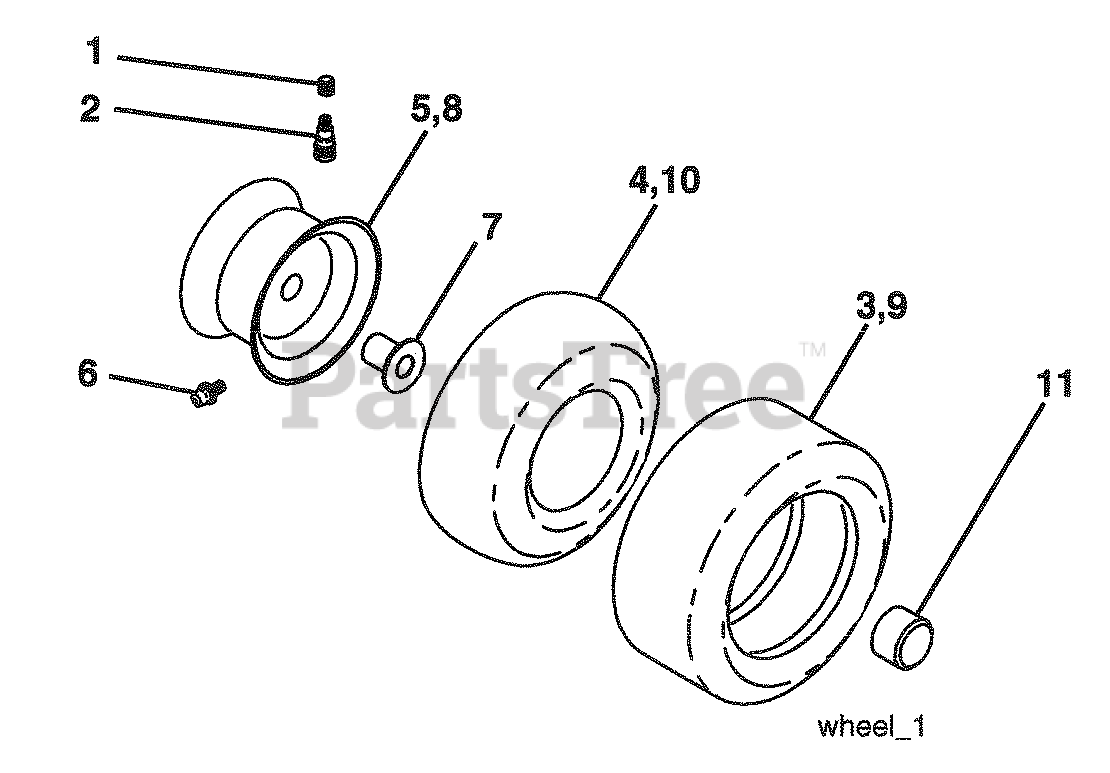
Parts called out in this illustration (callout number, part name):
1	Cap, Tire valve
2	Stem, Valve
4	Tube, Front
5	Rim assembly, 6"front
6	Fitting, Grease
7	Bearing, Flange
8	Rim assembly, 8" rear
9	Tire, Rear
10	Tube, Rear
11	Cap, Hub Axle
11	Sealant, Tire (10 oz.Tube)
